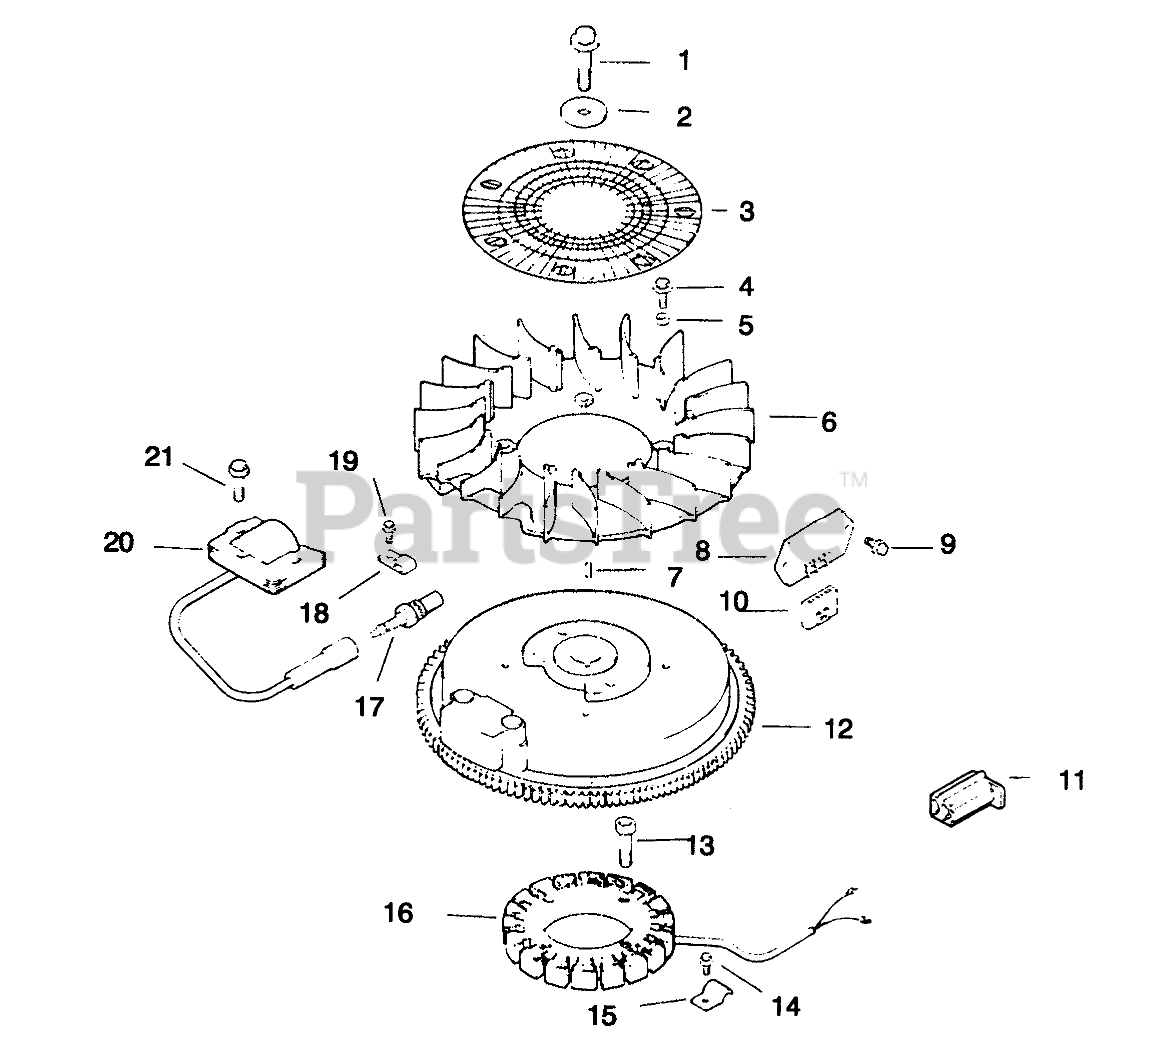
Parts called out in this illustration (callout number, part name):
1	Screw-Flywheel
2	Washer-Flywheel
3	Screen-Grass
4	Screw
7	Key
8	Rectifier-Unregulated
9	Screw
10	Connector
11	Connector
12	Flywheel Assembly
13	Screw
14	Screw
15	Clip-Stator Harness
16	Stator-15 amp
17	Spark Plug
18	Clip
19	Screw
20	Module-Ignition
21	Screw
